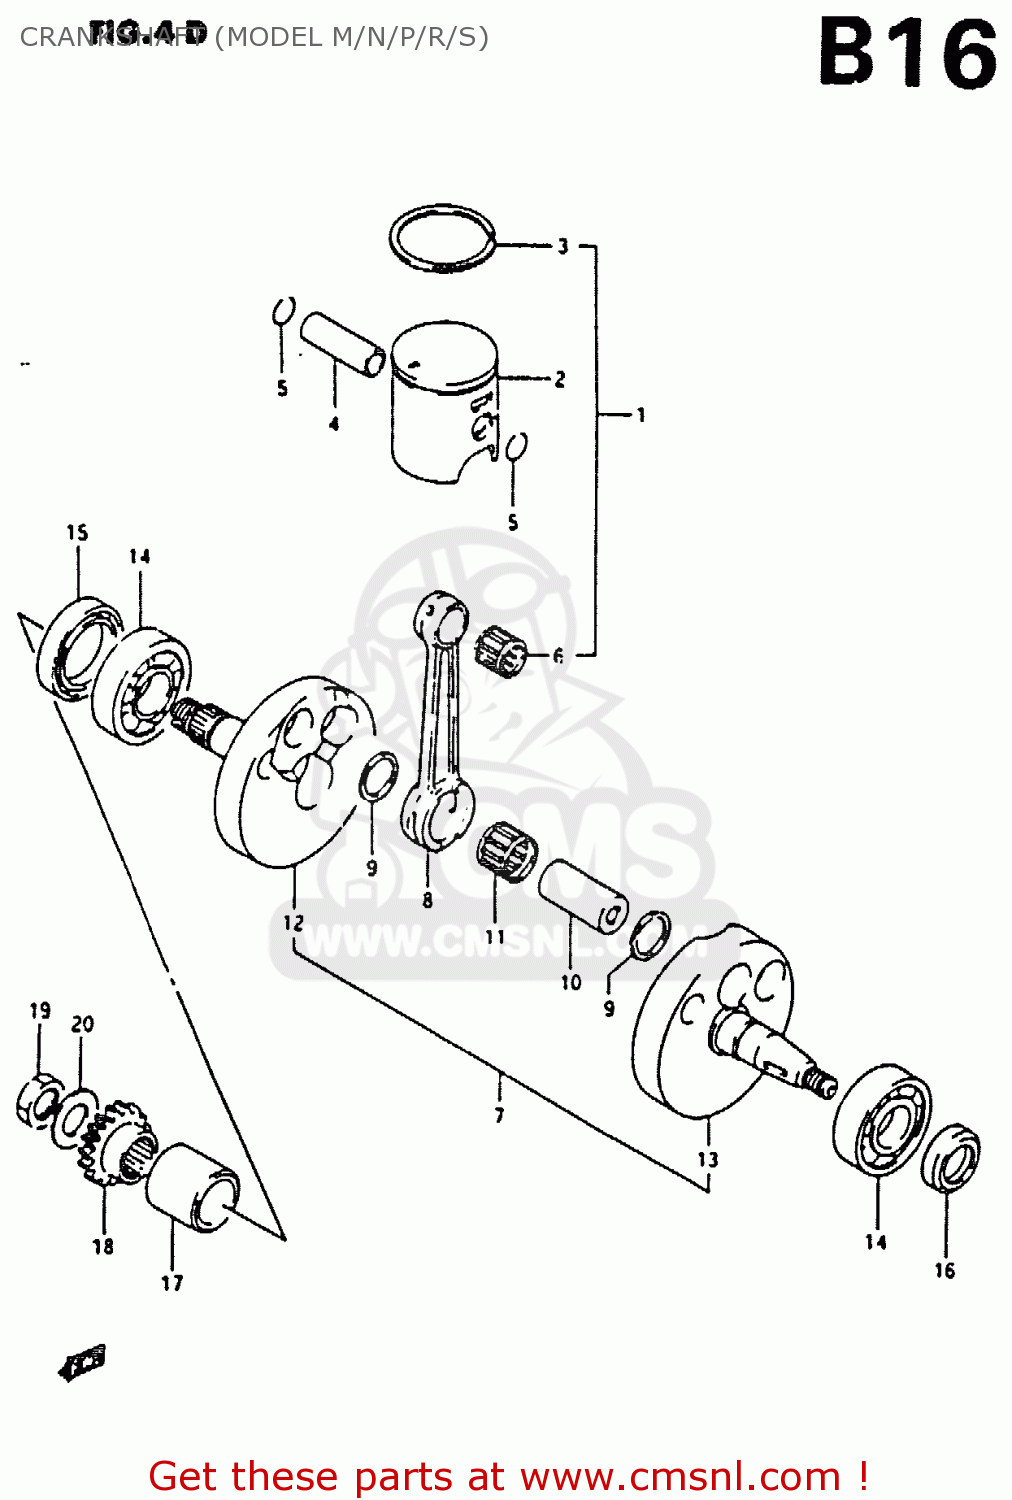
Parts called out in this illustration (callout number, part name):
1	PISTON KIT
2	PISTON
3	RING,PISTON
4	PIN,PISTON
5	RING,SNAP 14MM
6	BEARING(14X18X16)
7	CRANKSHAFT ASSY
8	ROD,CONNECTING
9	WASHER
10	PIN,CRANK
11	BEARING(20X26X13.7)
12	CRANKSHAFT,RIGHT
13	CRANKSHAFT,LEFT
14	BEARING
15	SEAL,OIL(30X40X7)
16	SEAL,OIL(18X30X6)
17	SPACER,PRIMARY DRIVE GEAR
18	GEAR,PRIMARY DRIVE (NT:
19	NUT
20	WASHER
21	WASHER
22	WASHER
